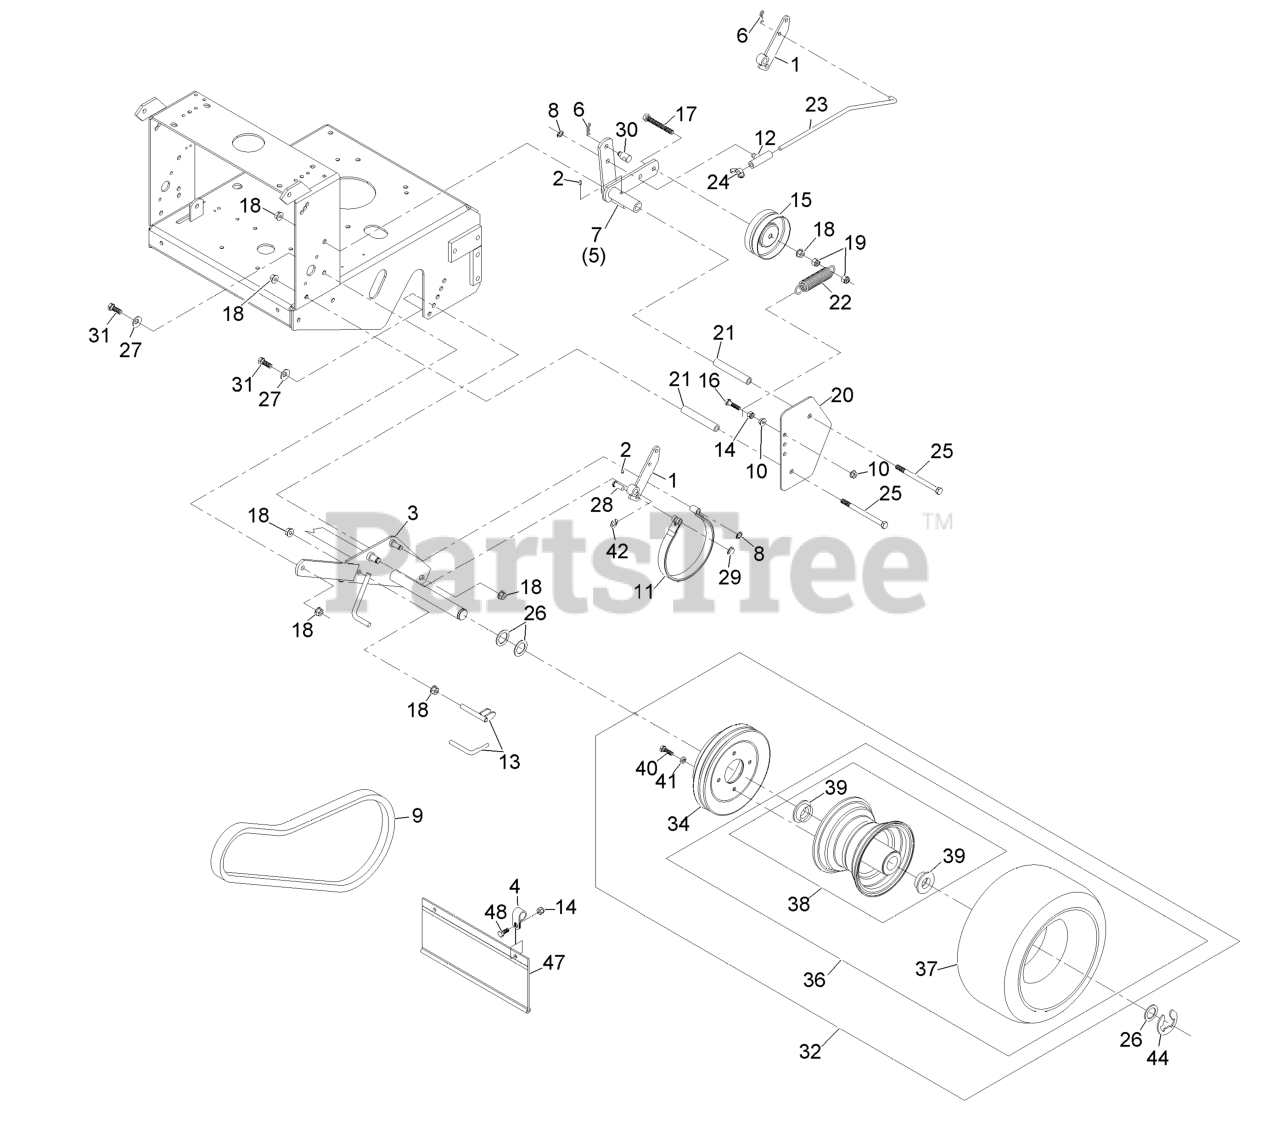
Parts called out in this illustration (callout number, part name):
1	ARM-BRAKE
2	FITTING-GREASE
3	AXLE
4	CLAMP-R
6	PIN-COTTER
8	RING-RETAINING
9	BELT,WHEEL DRIVE
10	NUT-HF
11	BAND-BRAKE
12	SWIVEL-BRAKE
13	SCRAPER
14	NUT-LOCK, NI
15	IDLER-WHEEL, DRIVE
16	SCREW-HH
17	SCREW-HH
18	NUT-HHF, WHIZ
19	NUT-LOCK, NI
20	SHIELD-WHEEL, DRIVE
21	SPACER-SHIELD
22	SPRING-EXTENSION
23	LINKAGE-BRAKE, LH
23	LINKAGE-BRAKE, RH
24	WINGNUT-NYLOCK
25	SCREW-HH
26	WASHER-SPACER
27	WASHER-BELLEVILLE
28	PIN-CLEVIS
29	RING-RETAIN,PUSH,EXT,FLAT
30	SWIVEL-DRIVE LEVER, 3/8 L
31	SCREW-HH
32	DRIVE WHEEL ASM
34	DRUM AND SHEAVE ASM
36	WHEEL AND TIRE ASM
37	TIRE-TURFMASTER
38	WHEEL AND HUB ASM
39	BEARING-FLANGED
40	SCREW-HH
41	WASHER-LOCK
42	RING-RETAINING, EXTERNAL
44	RING-SNAP
47	SHIELD-TRAILING
48	SCREW-HH
